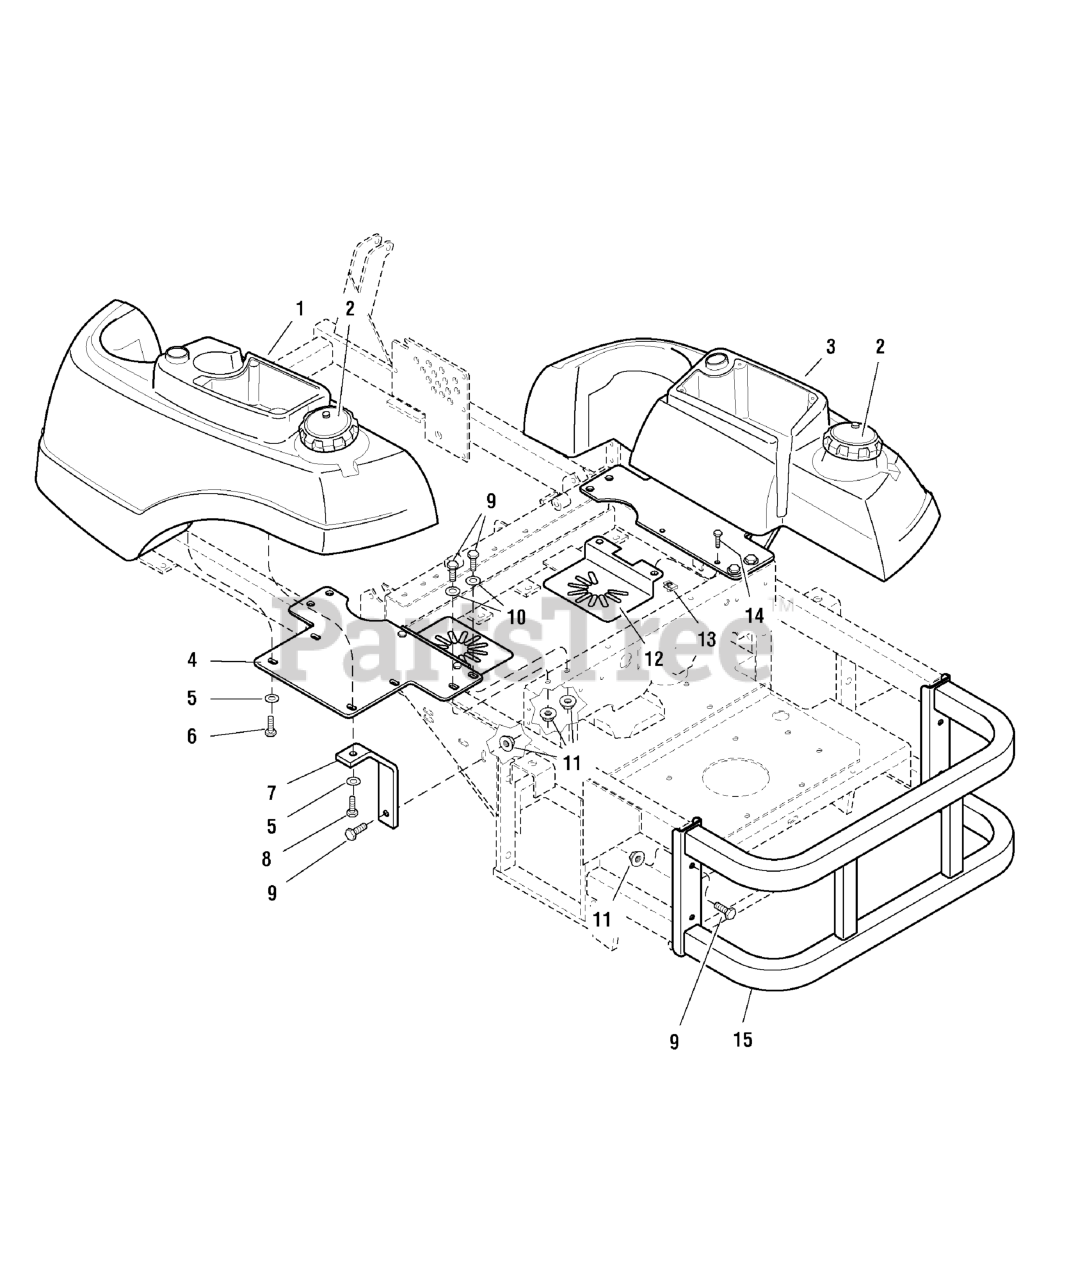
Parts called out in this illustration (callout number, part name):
1	FUEL TANK, IS3000Z, LH
2	CAP, FUEL TANK, 3-1/2 NECK
3	FUEL TANK, IS3000Z, RH
4	FUEL TANK MOUNT
5	WASHER, 5/16" SAE
6	BOLT, 5/16-18 X 3/4 GD5
7	TANK MOUNT SUPPORT
8	BOLT, 5/16-18 x 1-1/4
9	BOLT, 3/8-16 X 1" GD5 CZ
10	WASHER, 3/8 SAE
11	NUT, 3/8-16 Hex Serrated Flange
12	FAN SHIELD
13	BODY CLIP, 1/4-20
14	BOLT, 1/4-20 x 3/4
